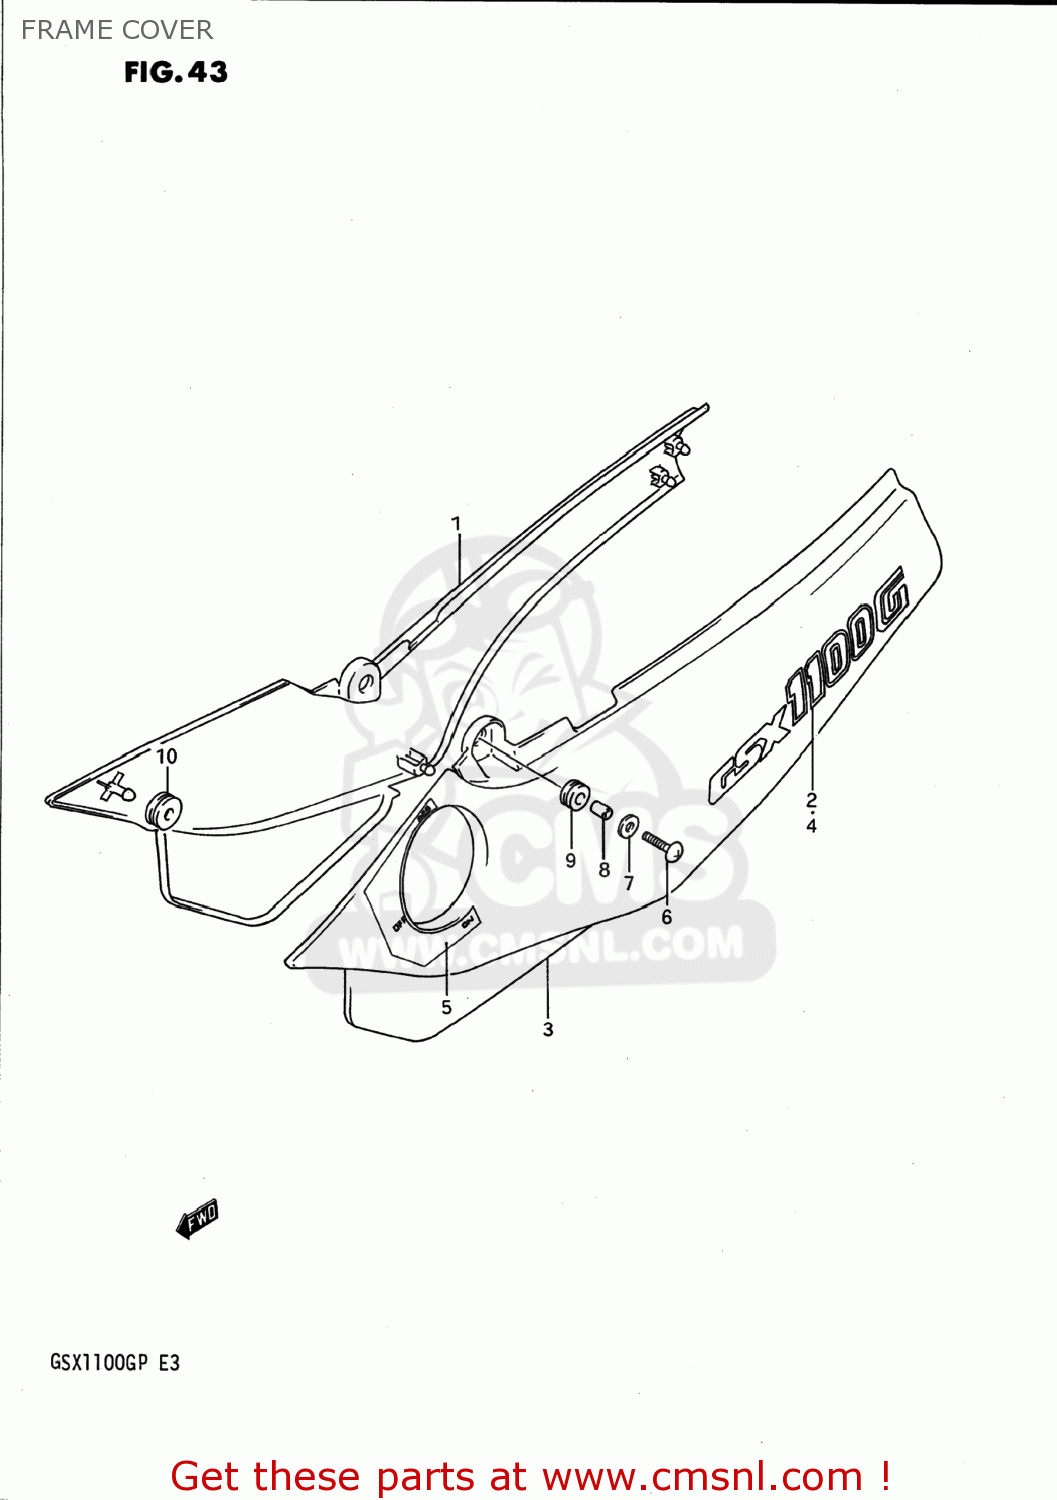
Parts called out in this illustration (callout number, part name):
1	COVER COMP,FRAME,RIGHT
2	EMBLEM,FRAME COVER
3	COVER COMP,FRAME,LEFT
4	EMBLEM,FRAME COVER
5	LABEL,FUEL COCK
6	SCREW, CENTER
7	WASHER(6.5X18X1)
8	SPACER
9	CUSHION
10	CUSHION
